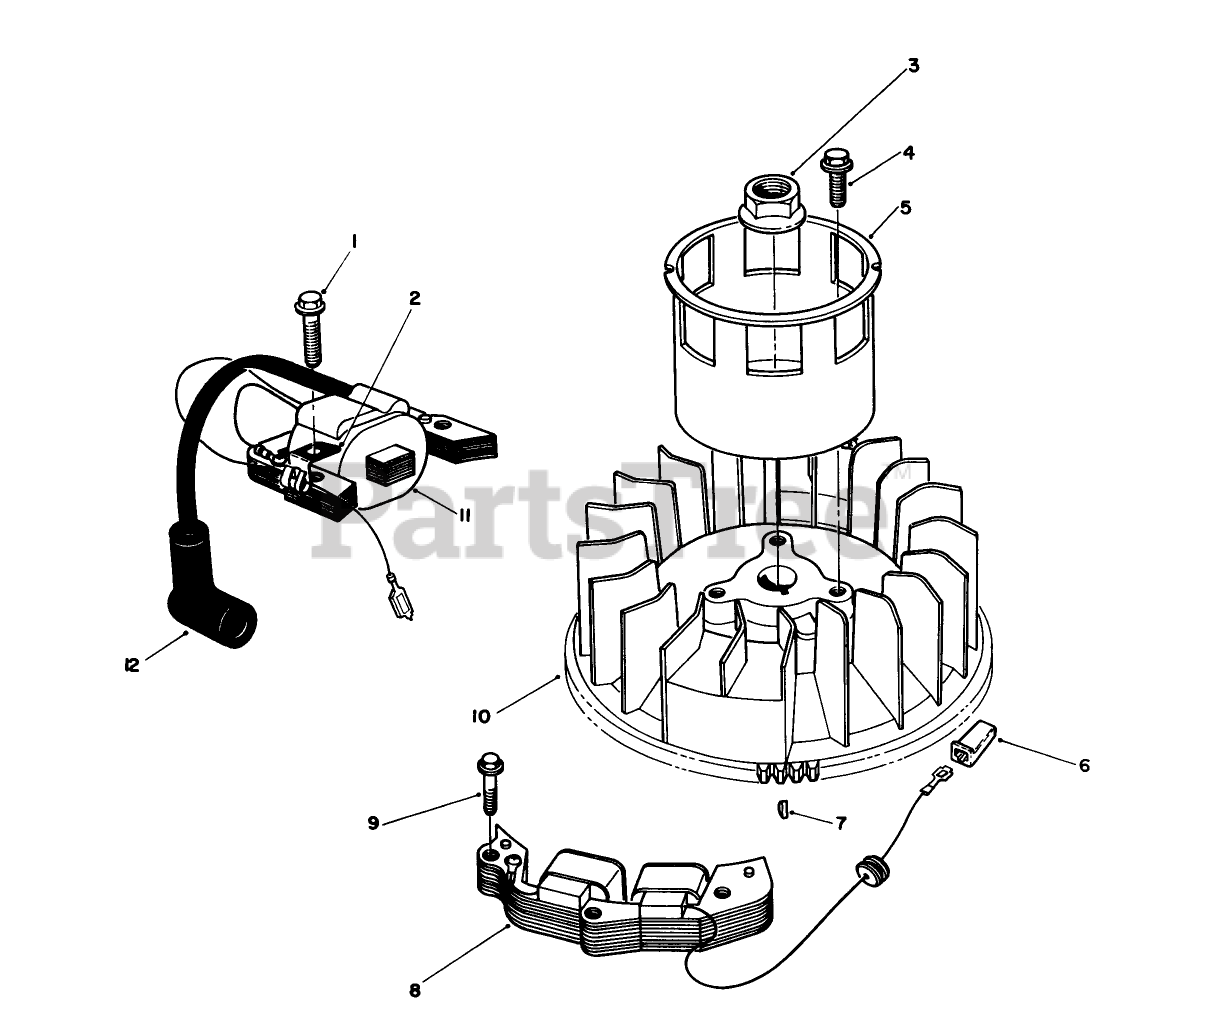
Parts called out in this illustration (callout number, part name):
2	CLAMP
6	CONNECTOR BODY
10	FLYWHEEL
11	COIL
12	COVER
